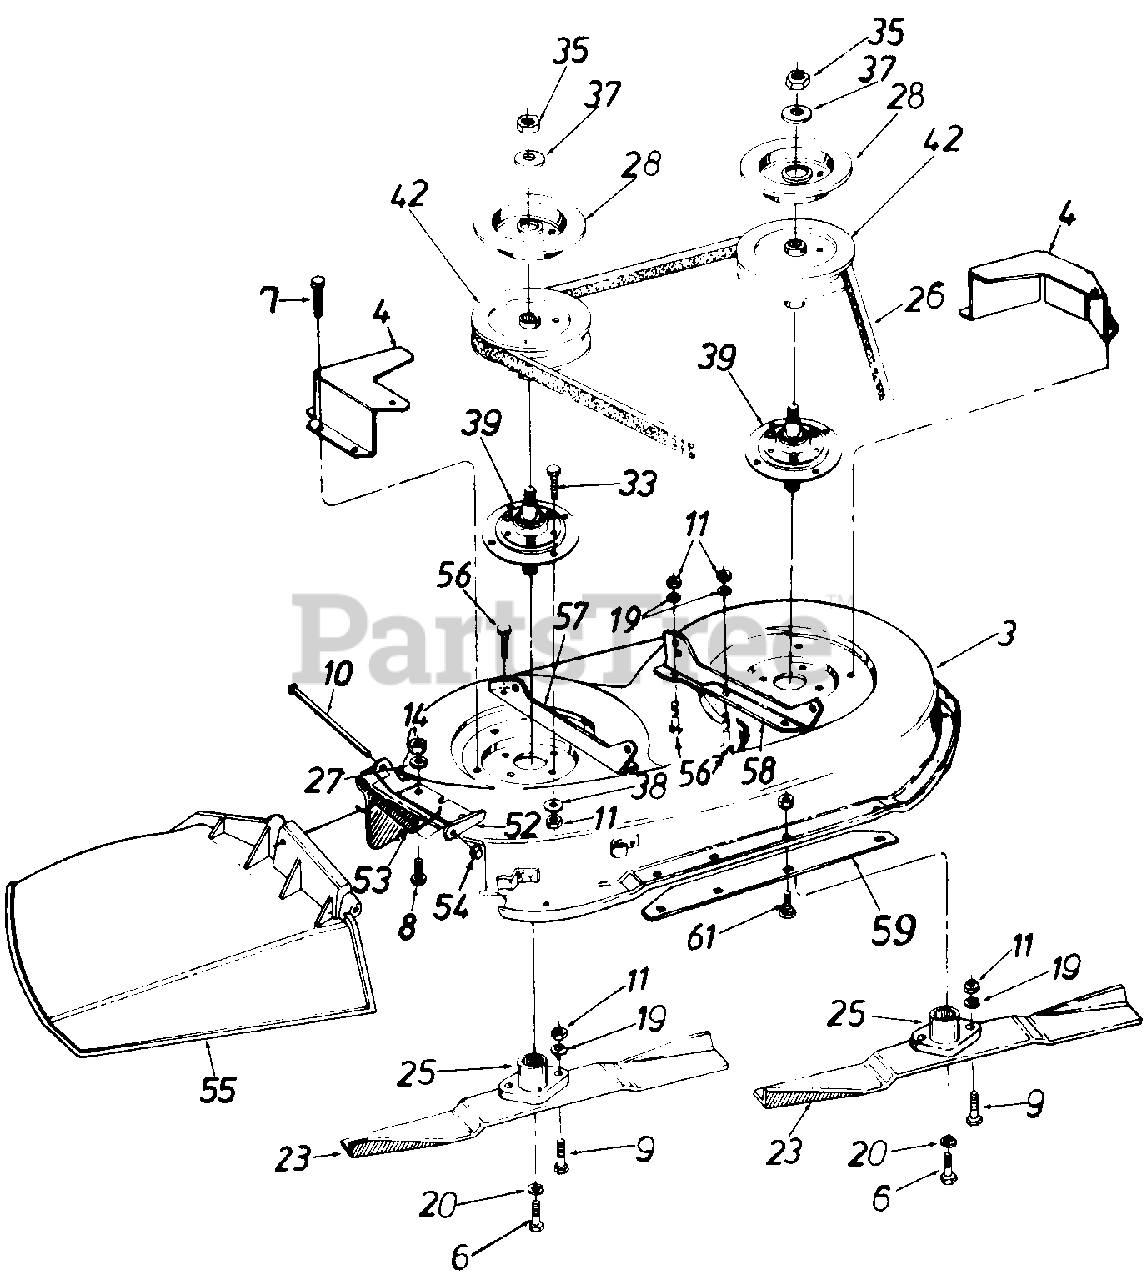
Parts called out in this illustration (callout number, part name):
3	38" Deck Ass'y. w/o Deck Wheels
6	Hex Bolt 3/8-24 x 1.0" Lg.
7	Hex Wash. Hd. TT-Tap Scr. l/4-20 Thd.
8	Hex Bolt 1/4-20 x .62"
9	Hex Bolt Special 5/16-24 x 1.0"
10	Hinge Pin
11	Hex Nut 5/16-24 Thd.
14	Hex Nut 1/4-20 Thd.
19	L-Wash. 5/16" I.D.
20	L-Wash. 3/8" I.D.-H.D.
23	High-Lift Blade
25	Blade Adapter
26	V-Belt
28	Brake Disc
33	Hex Bolt 5/16-24 x .75 Lg.
35	Hex Jam Nut 5/8-18 Thd.
37	L-Wash. 5/8 I.D.
38	Bell-Wash. 345n l.D. x .88 0 O.D.
39	Blade Spindle Ass'y. Comp. Incl. Ref. 33
42	5 Dia. Pulley
52	Hinge Mtg. Brkt.
53	Torsion Spring
55	Chute Ass'y. Comp.
56	Hex Bolt 5/16-24 x .75 Lg.
